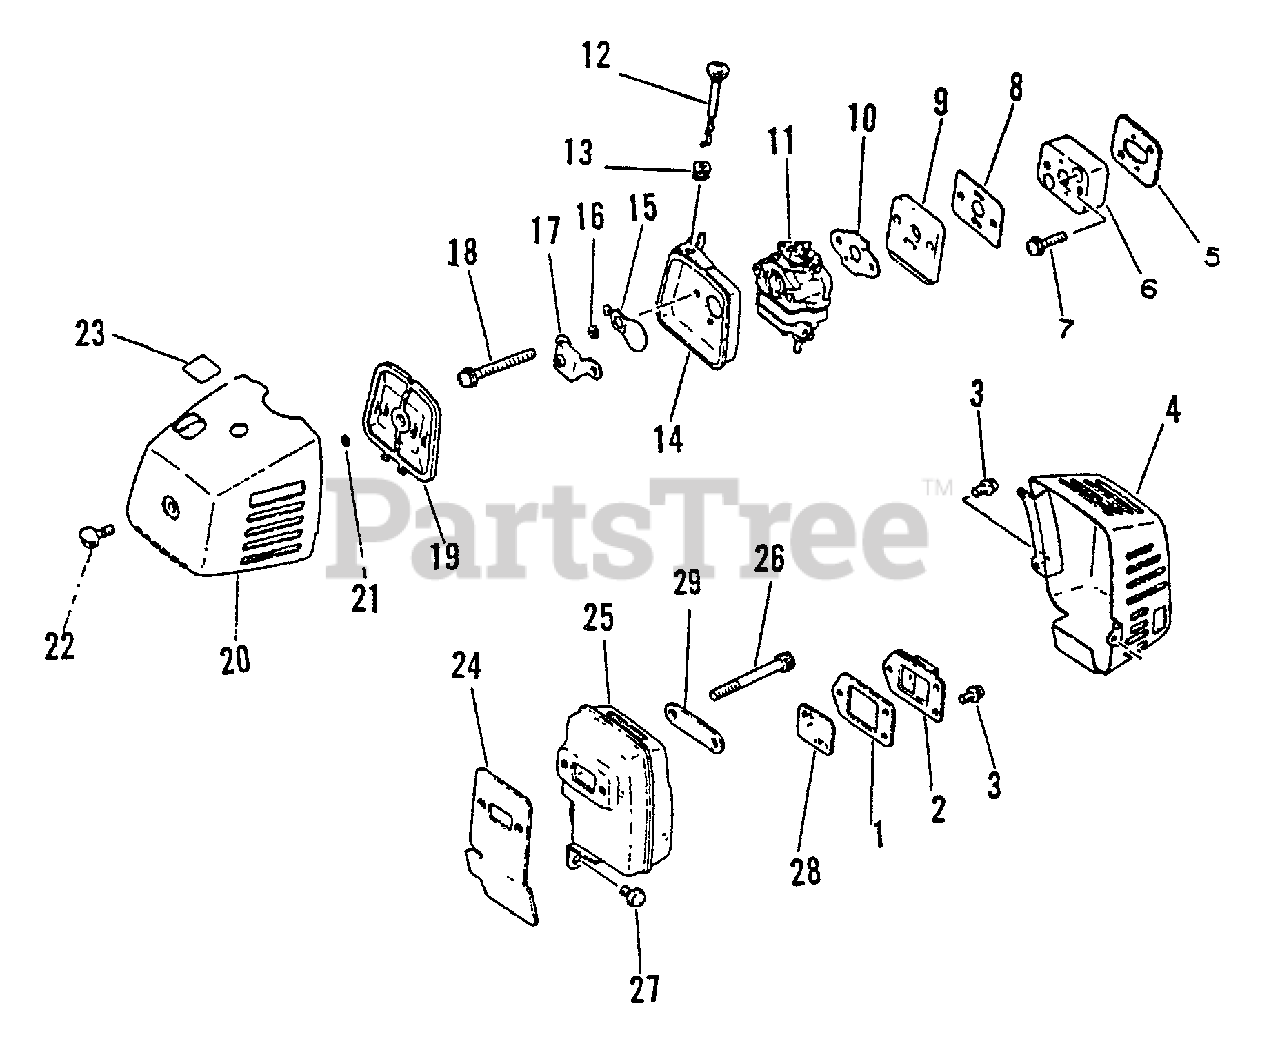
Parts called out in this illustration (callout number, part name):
1	GASKET, EXHAUST
2	LID, MUFFLER
3	SCREW 4×8
4	COVER, EXHAUST
5	GASKET, INTAKE
6	INSULATOR
7	SCREW 5×20
8	GASKET
9	PLATE
11	CARBURETOR
12	ROD, CHOKE
13	GROMMET, CHOKE
14	CASE, AIR FILTER
15	SHUTTER, CHOKE
16	WASHER 5.2×8×0.8T
17	PLATE, PREVENT
18	SCREW 5×50
19	FILTER, AIR
20	AIR FILTER COVER ASSY
23	LABEL, CHOKE
24	GASKET, MUFFLER
25	MUFFLER
26	BOLT 5×55
27	SCREW 5×10
28	SCREEN, SPARK ARRESTER
